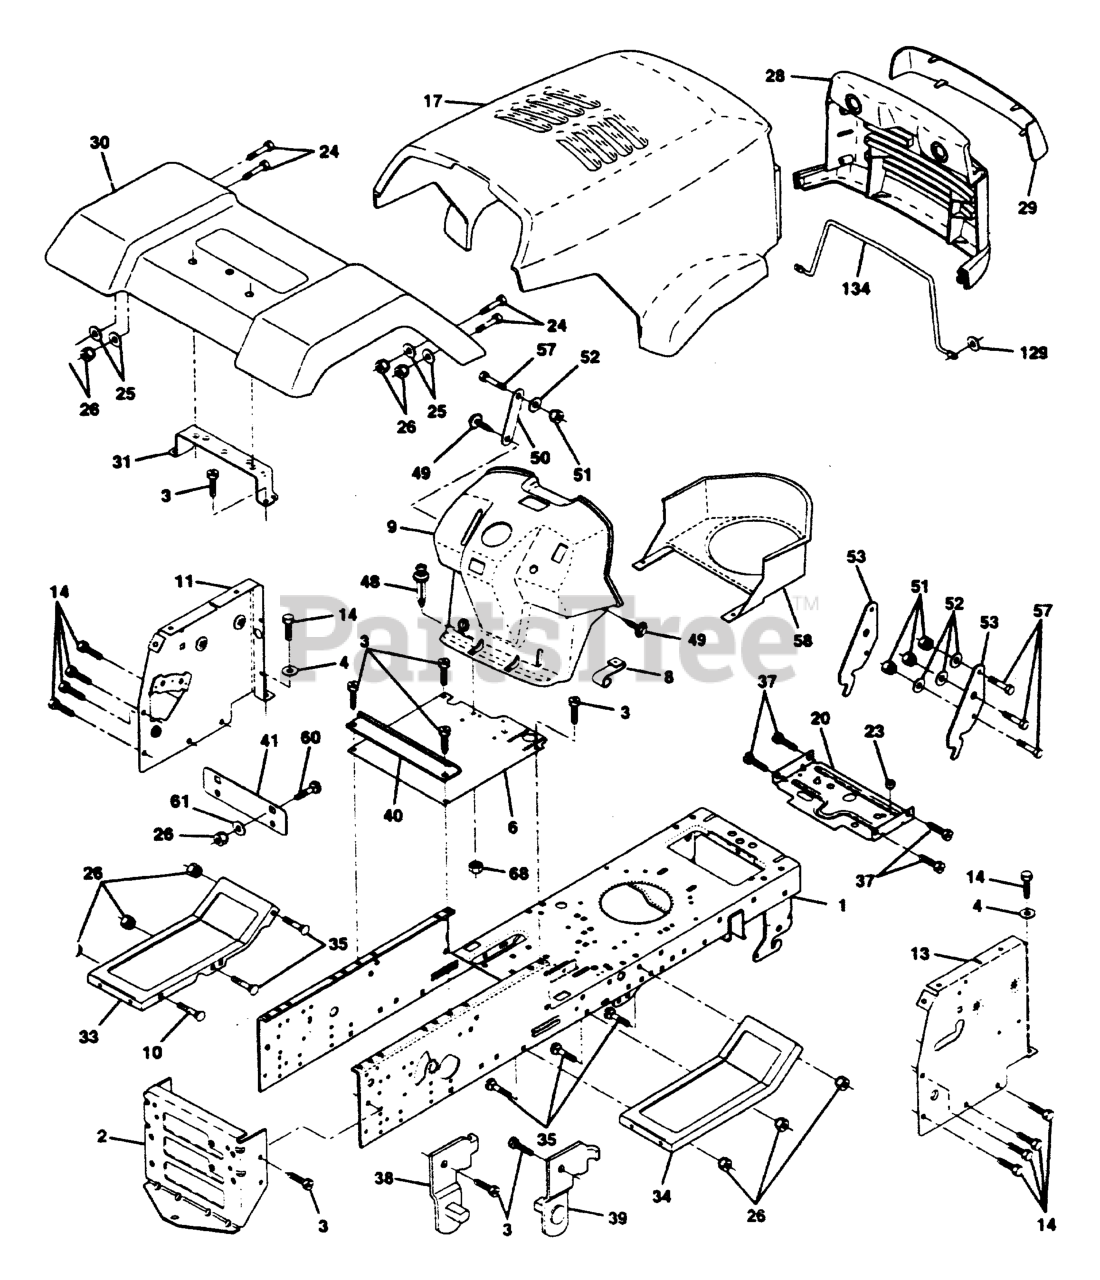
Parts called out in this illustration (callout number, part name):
1	CHASSIS WELD 11GA.95
2	STRETCH DRAWBAR
3	SCREW
4	WASHER
6	SADDLE LT FENDER
8	CLIP,INSULATOR
10	BOLT D
11	PANEL PNT DASH LH
13	PANEL DASH RH
17	HOOD LT/PL HUSQVARNA
20	PLATE MTG BATTERY FUEL TAND
23	BUSHING.SNAP.NYL.BLK.
25	WASHER
26	NUT
28	GRILLE LT/PL HUSQVARNA
29	LENS LT/PL HUSQVARNA
30	FENDER
31	BRACKET.SUPPORT.FENDER
33	FOOT REST LH
34	FOOTREST RH
37	Screw 5/16-18 x 1/2 Hex, Self Tapping 5/16-18 x 1/2
38	BRACKET LH PIVOT
39	BRACKET RH PIVOT
41	PLATE
48	RIVET PUSH
49	SCREW HEX CRT
51	NUT.CROWNLOCK.1/4
53	BRACKET PNT PICK OFF LT/PL
57	BOLT
58	AIR DUCT P/L/LT
60	Bolt - Rd. Hd. Sq. Neckiage 3/8 16 x 3/4
61	Washer 1 17/32 X 7/8 X 16 Ga
68	NUT
134	ROD SUPPORT HOOD LT/PL HUSQ
